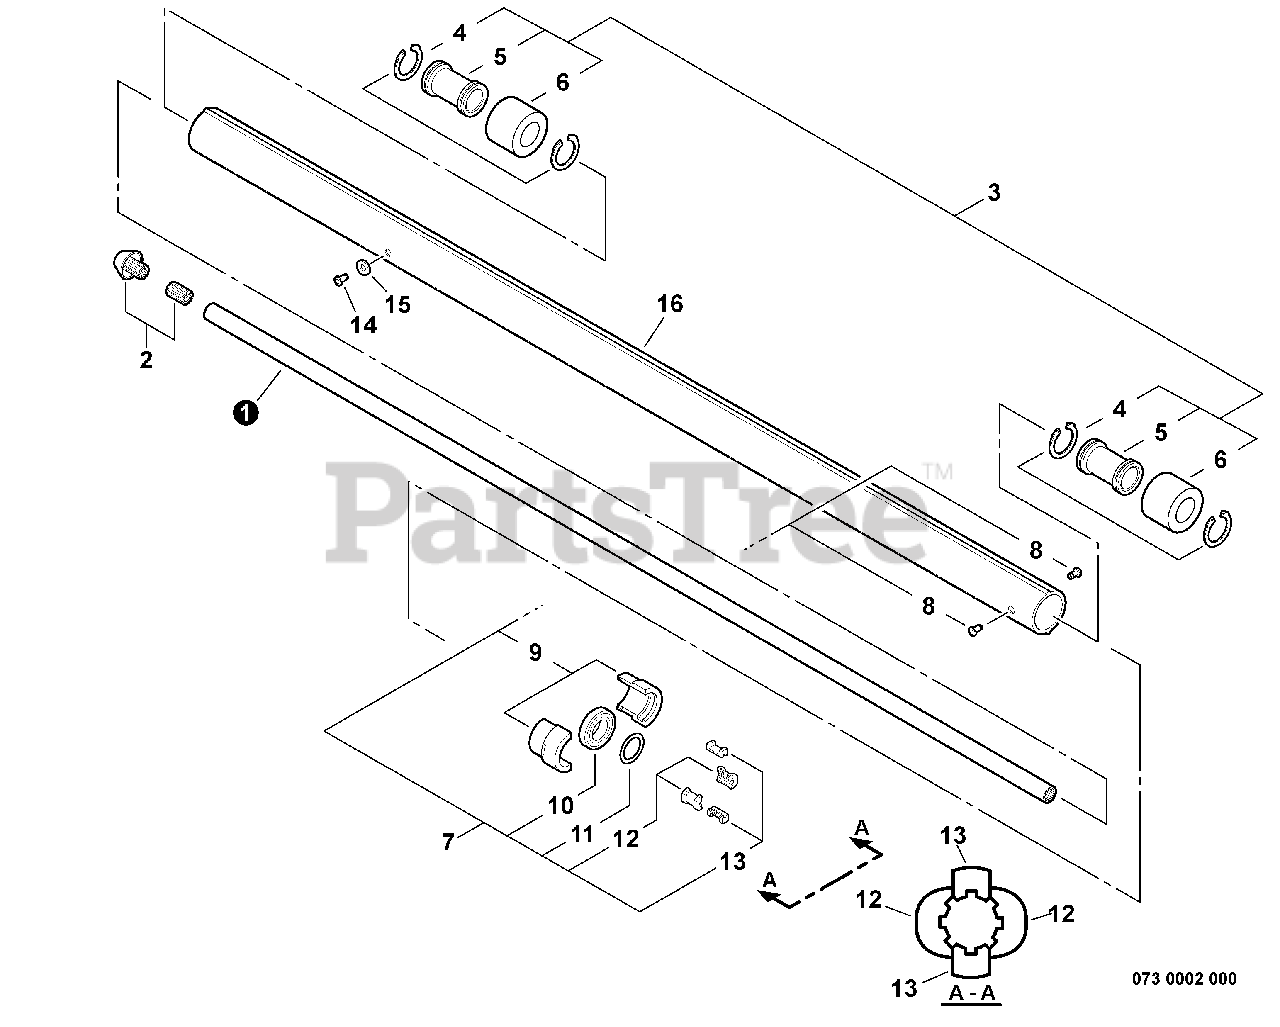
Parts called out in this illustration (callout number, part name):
1	DRIVESHAFT
2	ADAPTER, UPPER DRIVE SHAFT
3	DRIVESHAFT GUIDE ASSY
4	RING, RETAINING
5	GUIDE, SHAFT
6	PAD, FOAM
7	HOLDER ASSY, BEARING
9	HOLDER, BEARING
10	BEARING, BALL 6002 DDU
11	WASHER, WAVE
12	GUIDE, SHAFT - LARGE
13	GUIDE, SHAFT - SMALL
15	WASHER, FLAT 5
16	PIPE, MAIN
